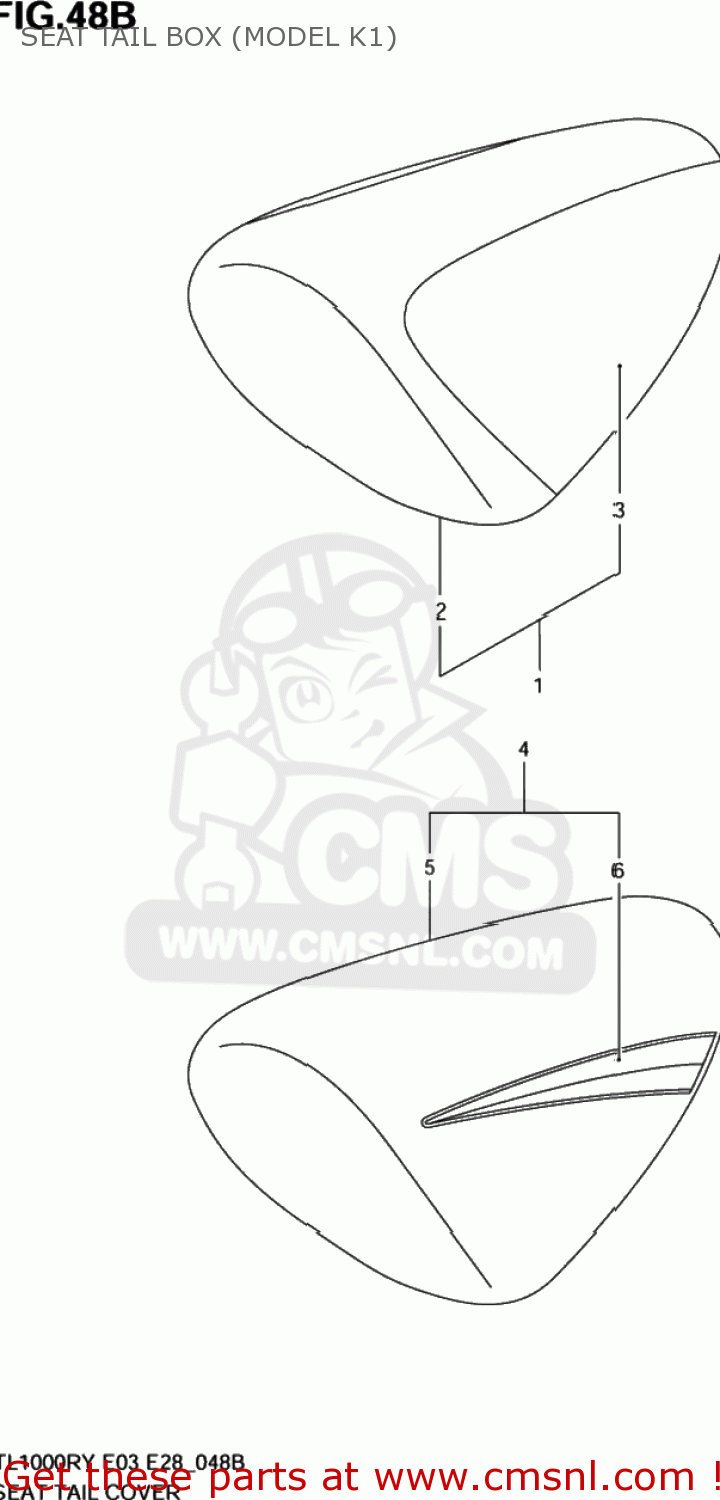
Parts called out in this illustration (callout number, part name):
1	BOX ASSY,SEAT TAIL(BLACK)
2	BOX,SEAT TAIL(BLACK)
3	TAPE SET,BOX SEAT TAIL(WHITE)
4	BOX ASSY,SEAT TAIL(YELLOW)
5	BOX,SEAT TAIL
6	TAPE SET,BOX SEAT TAIL
